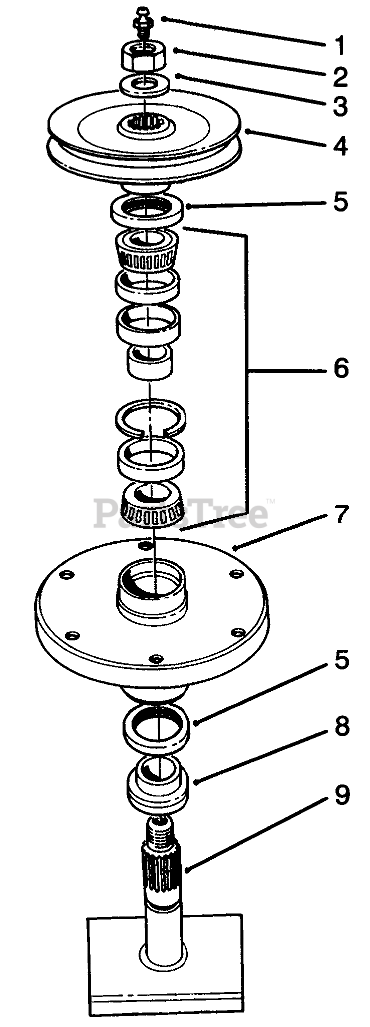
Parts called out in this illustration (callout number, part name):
1	FITTING-GREASE
2	NUT-HEX
3	WASHER
4	PULLEY AND HUB ASM
5	SEAL-OIL
6	BEARING ASM
7	HOUSING-SPINDLE
8	SPACER
9	SHAFT
